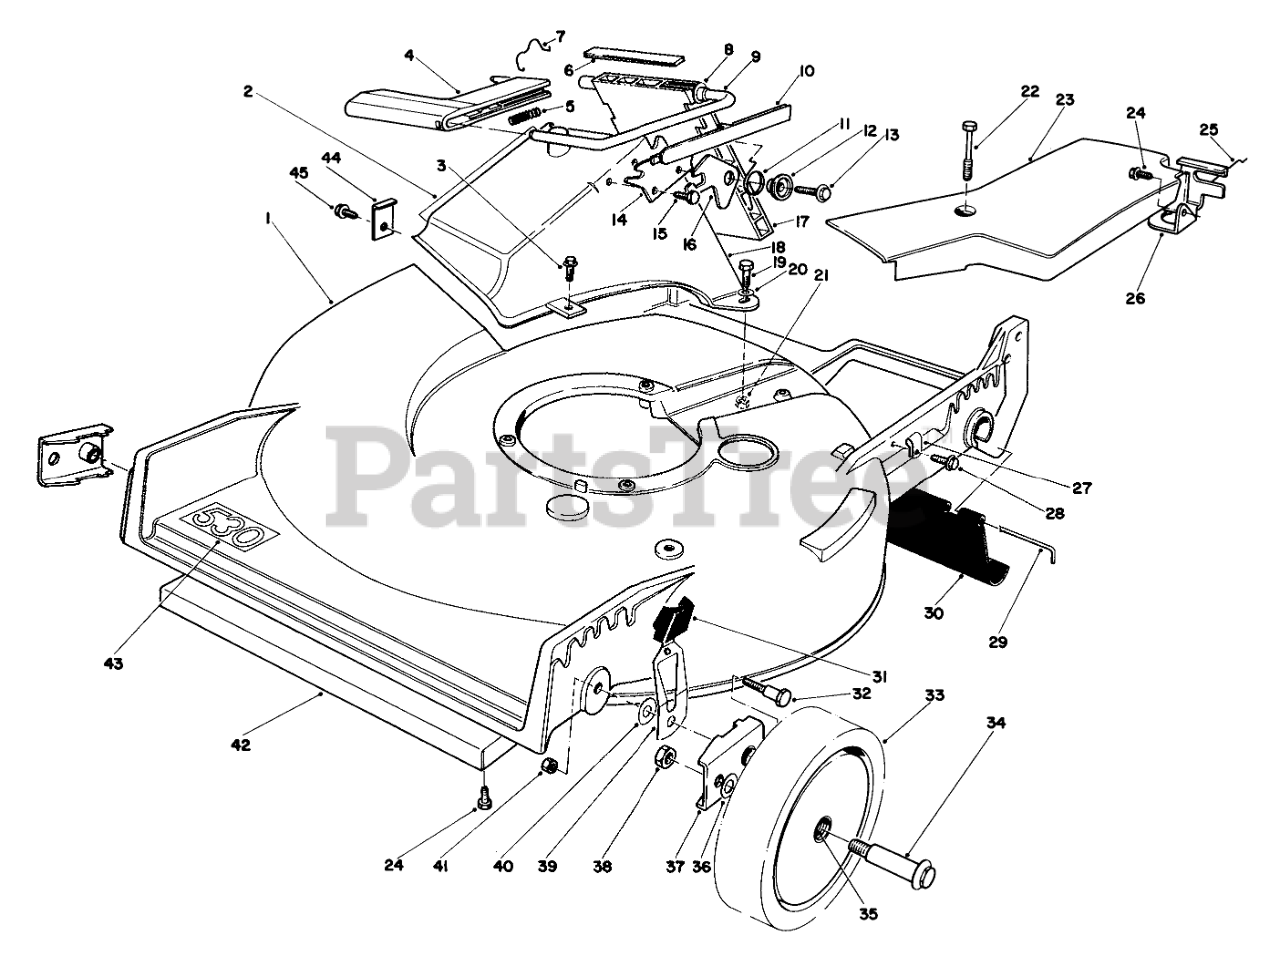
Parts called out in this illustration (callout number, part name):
1	21 SP RB HSG/DECAL
2	ATTENTION DECAL
3	Screw
4	Handle-Door
5	Spring
6	DOOR COVER
7	DOOR RET SPRING
8	BUSHING-NYLON
9	DOOR ROD +
10	DOOR HANDLE COVER
11	TORSION SPRING
12	DOOR SPACER
13	SCREW-HWH
14	DOOR LATCH PLATE
15	SCREW-PLASTITE
16	SAFETY LATCH
17	Door Discharge
18	Tunnel Discharge
19	SCREW-HH
20	WASHER-FLAT
21	NUT-LOCK, NI
22	SCREW-HHFTF
23	Cover-Belt
24	SCREW-HWHTF
25	RETAINER-CABLE
26	Bracket-Traction Adj.
27	CLAMP-CABLE
28	SCREW
29	ROD-SHIELD
30	SHIELD-TRAILING
31	KNOB-ARM
32	PIVOT SCREW
33	Wheel & Tire Assembly (Incl. Ref. #35)
34	BOLT-WHEEL
35	BUSHING
36	WASHER
37	HP PIVOT ARM ASM
38	Nut
39	Spring Arm
40	WASHER-PIVOT
41	NUT-LOCK, NI
42	Shield-front
43	Decal-530
44	TUNNEL CLIP
45	SCREW
